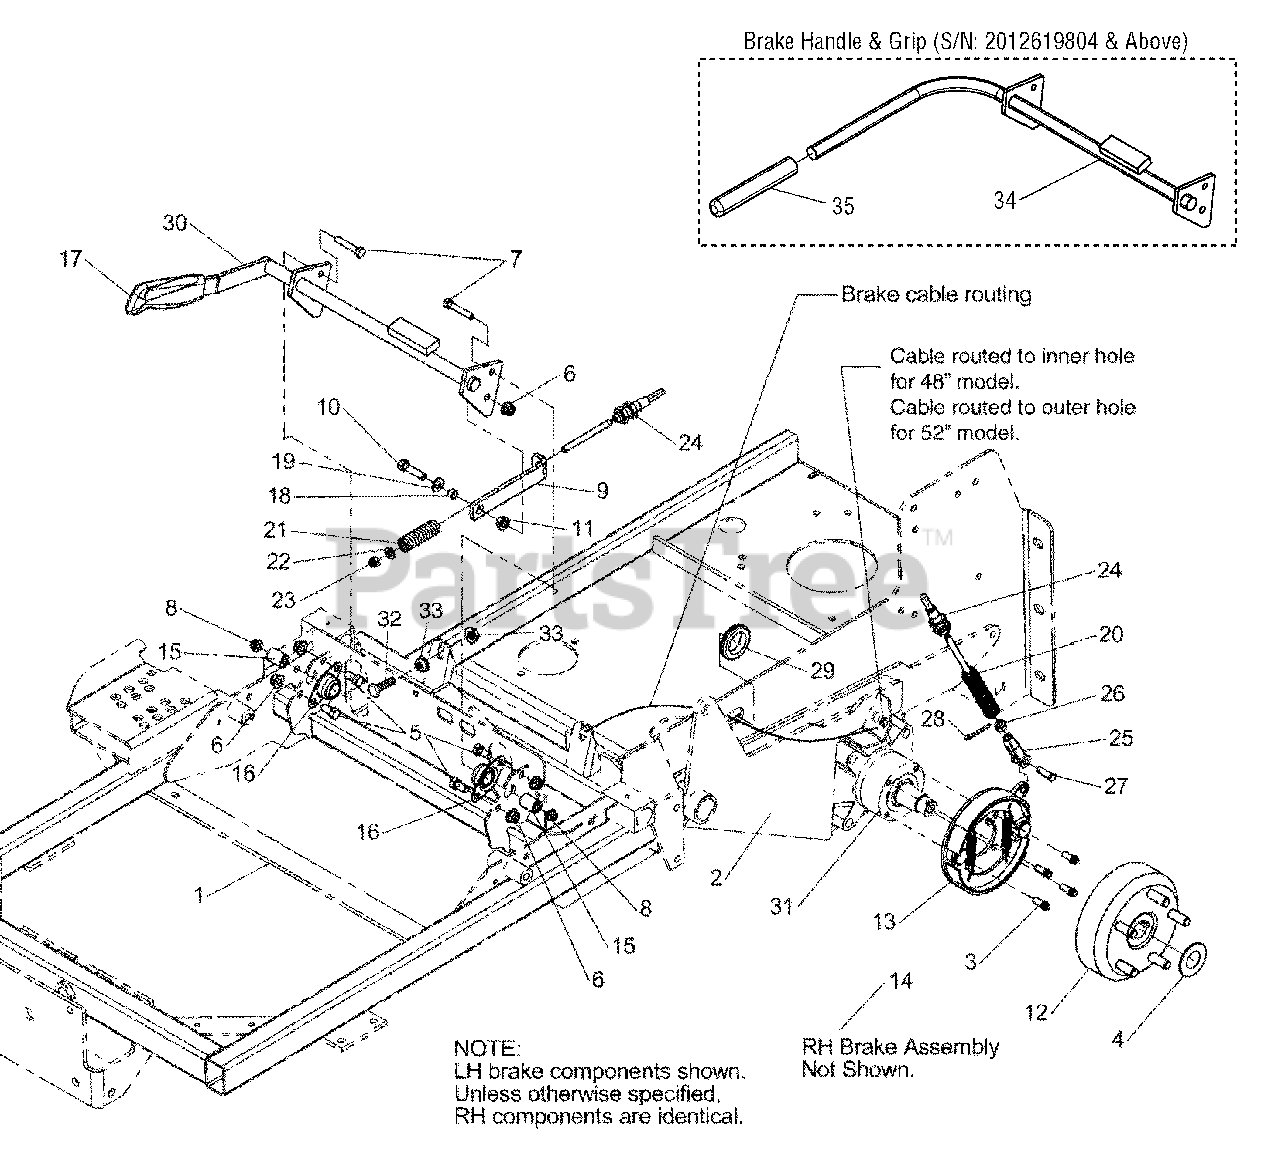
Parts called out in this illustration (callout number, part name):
1	MAIN FRAME
2	MOTOR MOUNT
3	BOLT, 5/16-18 X 3/4 12PT FLANGE - PATCH
4	WASHER, 1 x 2
5	BOLT, 3/8-16 X 3/4" GD5 YZ
6	NUT, 3/8 - 16 HEX NYLOCK FLANGE
7	BOLT, 5/16-18 X 1-3/4" GD5 YZ
8	NUT, 5/16-18 HEX NYLOCK FLANGE NUT
9	LINK, BRAKE STOP, 6.0 - BLK
10	BOLT, 3/8-16 X 1-1/2" GD5 YZ
11	NUT, 3/8-16 Hex Large Serrated Flange
12	BRAKE DRUM, 6", 5 BOLT, KNOTT
12	DRUM,1-1/4TAPER,5 BOLT
13	BRAKE SHOE ASM, LH, KNOTT
13	ASSM, BRAKE, 1-1/4 HUB, LH
15	SPACER, .32 X .75 X 1.06, PM
16	BEARING, BRONZE FLANGE, 3/4"
17	GRIP, BLACK FLEXIBLE
18	SPACER, .38 X .50 X .27, CZ
19	WASHER, 3/8 SAE
20	SPRING-COMP, .615ID X 4.00LG X .080WR
21	SPRING-COMP, .428IDX2.50LGX.154WR, BZ
22	WASHER, 5/16" SAE
23	NUT, Hex, Nylon Lock, 5/16-24
24	CABLE, PARKING BRAKE
25	CLEVIS, 5/16-24, Plastic
26	NUT, Hex, 5/16-24
27	PIN, CLEVIS, 5/16 X 1, PLATED
28	PIN, HAIR, .0585 X 1-1/8, 1/4 EYE, YZ
29	GROMMET, 1-1/4"
30	BRAKE SHAFT
31	WHEEL MOTOR
32	BOLT, 5/16-18 X 1-1/8 GD5 CZ
33	NUT, 5/16-18 HEX SERRATED FLANGE (LARGE)
34	WELD, BRAKE SHAFT - BLK
35	GRIP, FOAM, 3/4 ID X 6 X .187
